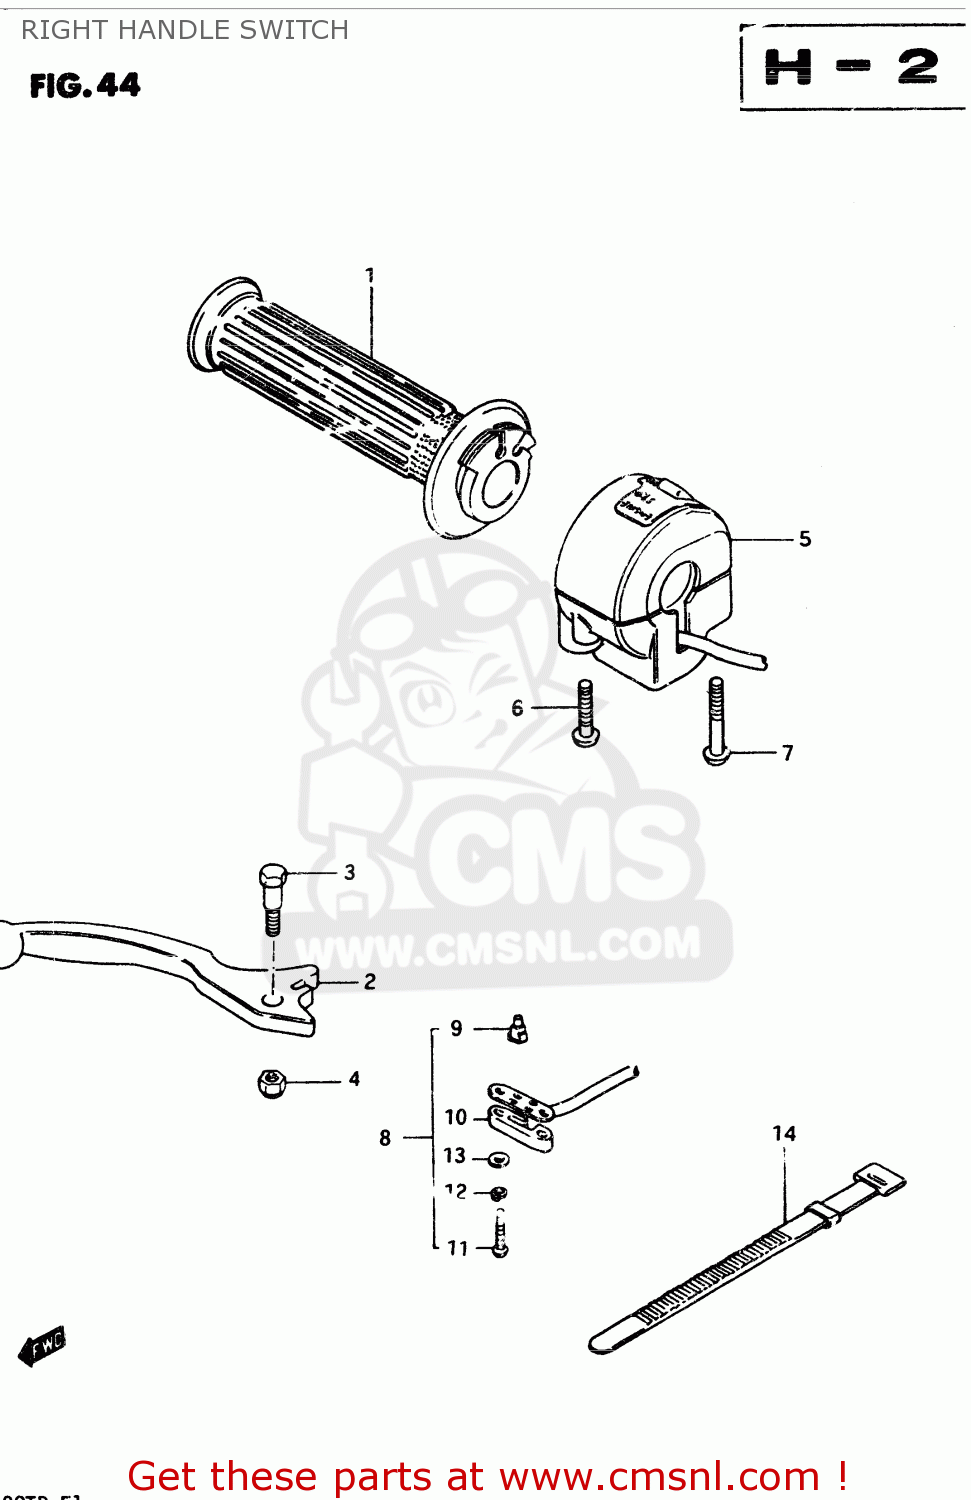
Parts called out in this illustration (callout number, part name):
1	GRIP,THROTTLE
2	LEVER,BRAKE
3	BOLT
4	NUT 6MM
5	SWITCH ASSY, HANDLE LH
6	SCREW
7	SCREW
8	SWITCH ASSEMBLY
9	CONTACT,SWITCH
10	COVER,FR BK TERMINAL BASE
11	SCREW
12	LOCK WASHER
13	WASHER
14	CLAMP(L:120)
